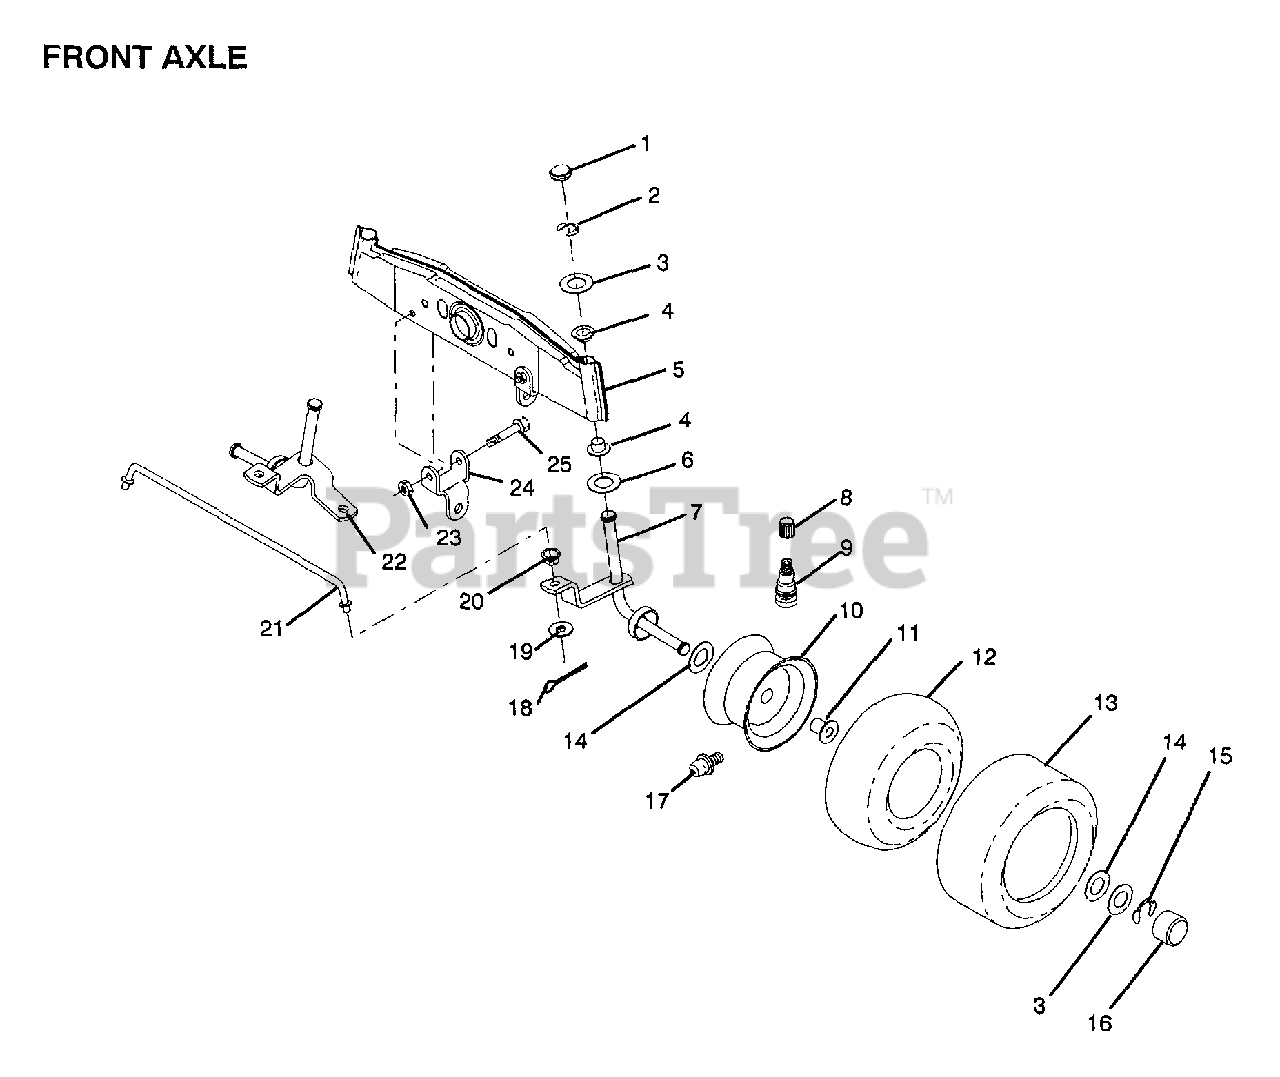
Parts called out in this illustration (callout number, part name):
1	CAP
2	RING
3	WASHER
4	NYLINER
5	AXLE FRONT
6	WASHER .T
7	SPINDLE RH
8	VALVE CAP
9	VALVE STEM LT
11	"FLANGE, BEARING"
12	TUBE.5.3/4.5/6
13	TIRE
14	WASHER
15	RING
16	HUB CAP
17	FITTING LT
18	COTTER PIN
19	WASHER
20	BUSHING.DRAGLINK
21	ROD TIE
22	SPINDLE LH
24	"BRKT,FRONT STAB"
25	BOLT
